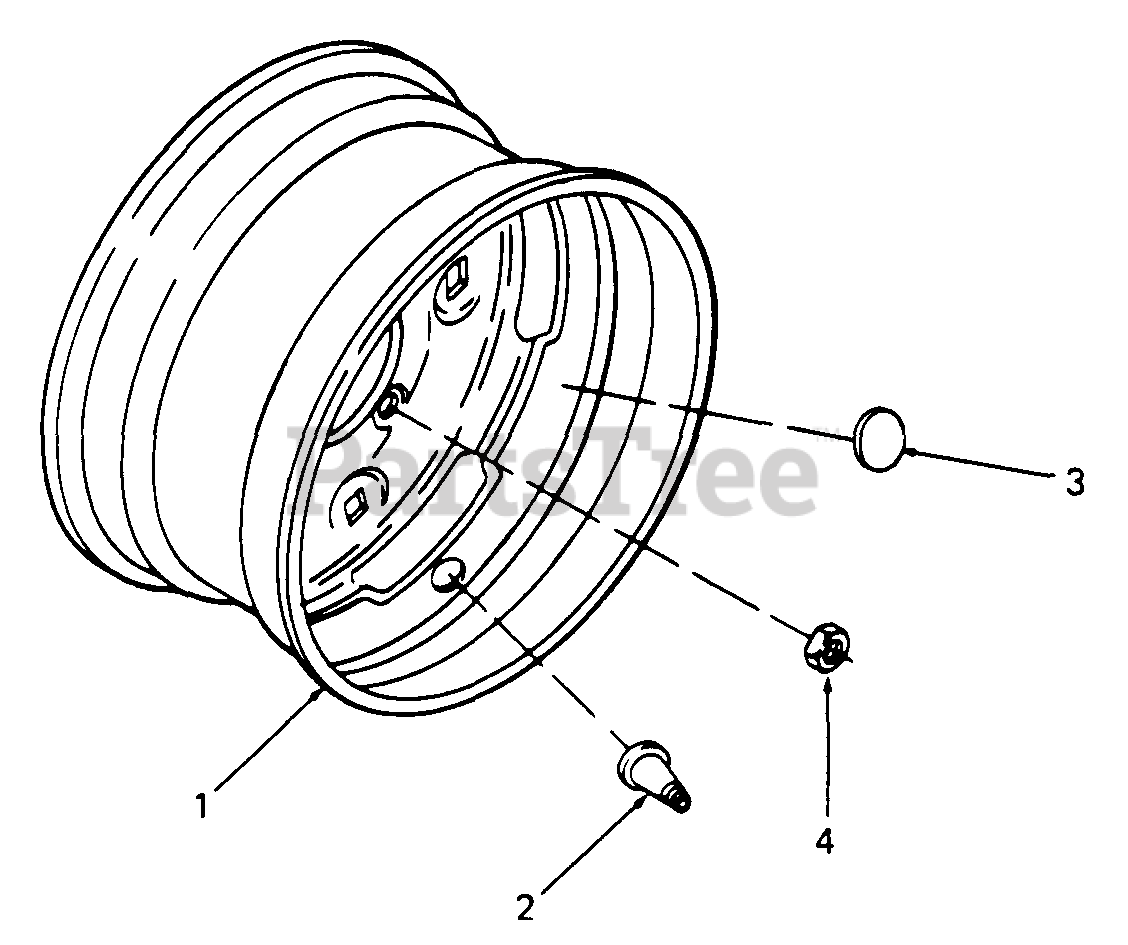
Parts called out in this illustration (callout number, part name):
2	Valve, Tubeless Air
3	Label, Inflation
4	Nut, Lug, 7/16-14,
